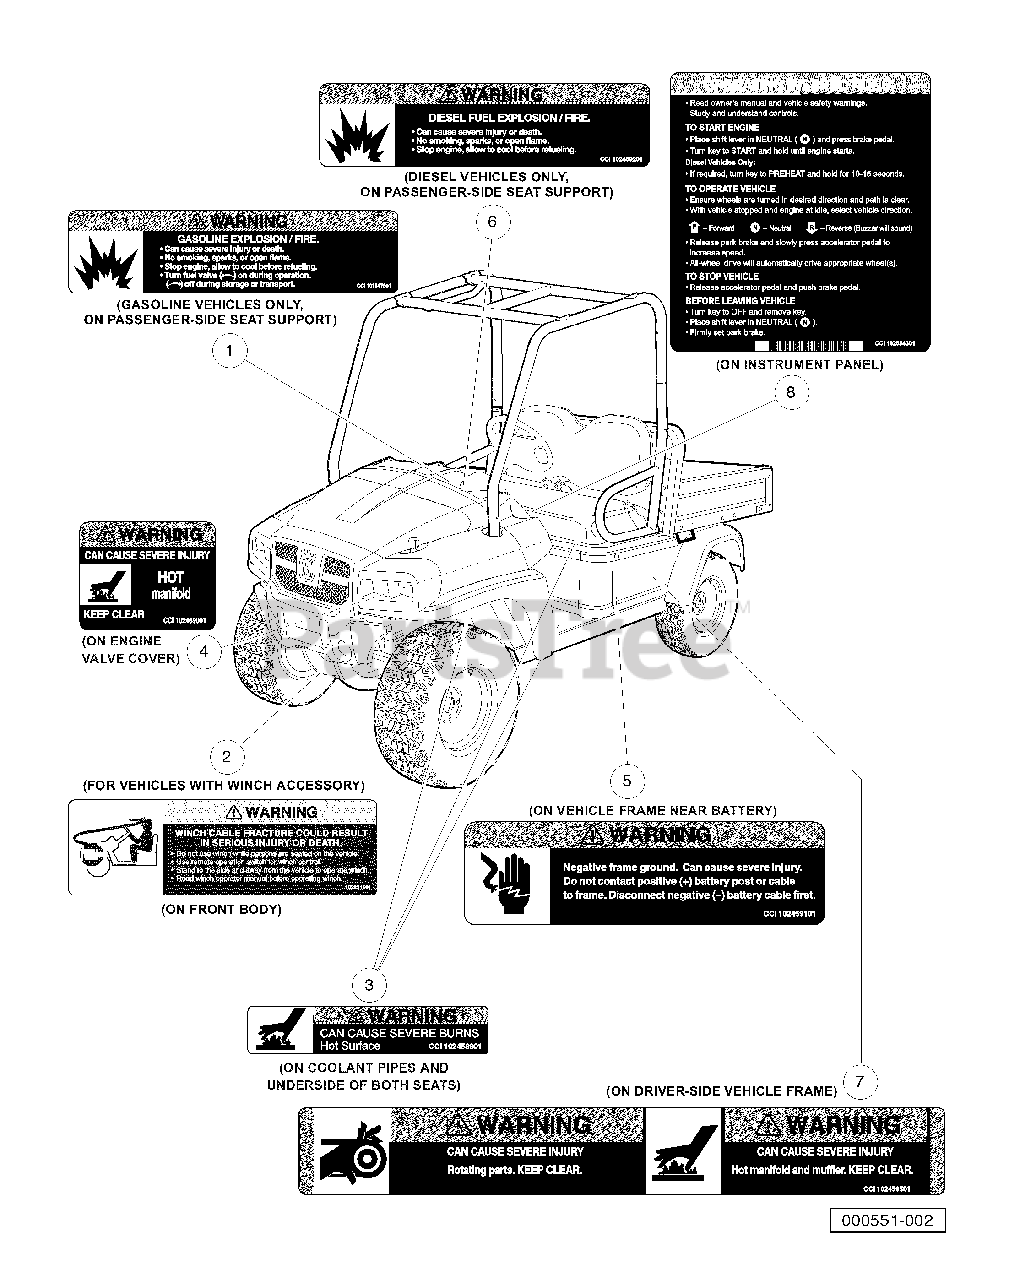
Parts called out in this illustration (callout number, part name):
1	Decal, Gasoline Explosion/Fire Warning
2	Decal, Winch Cable Fracture Warning
3	Decal, Hot Surface Warning
4	Decal, Hot Manifold Warning
5	Decal, Frame Ground Warning
6	Decal, Diesel Explosion/Fire Warning
7	Decal, Rotating Parts and Hot Exhaust Warning
8	Decal, Operating Instr, AWD
